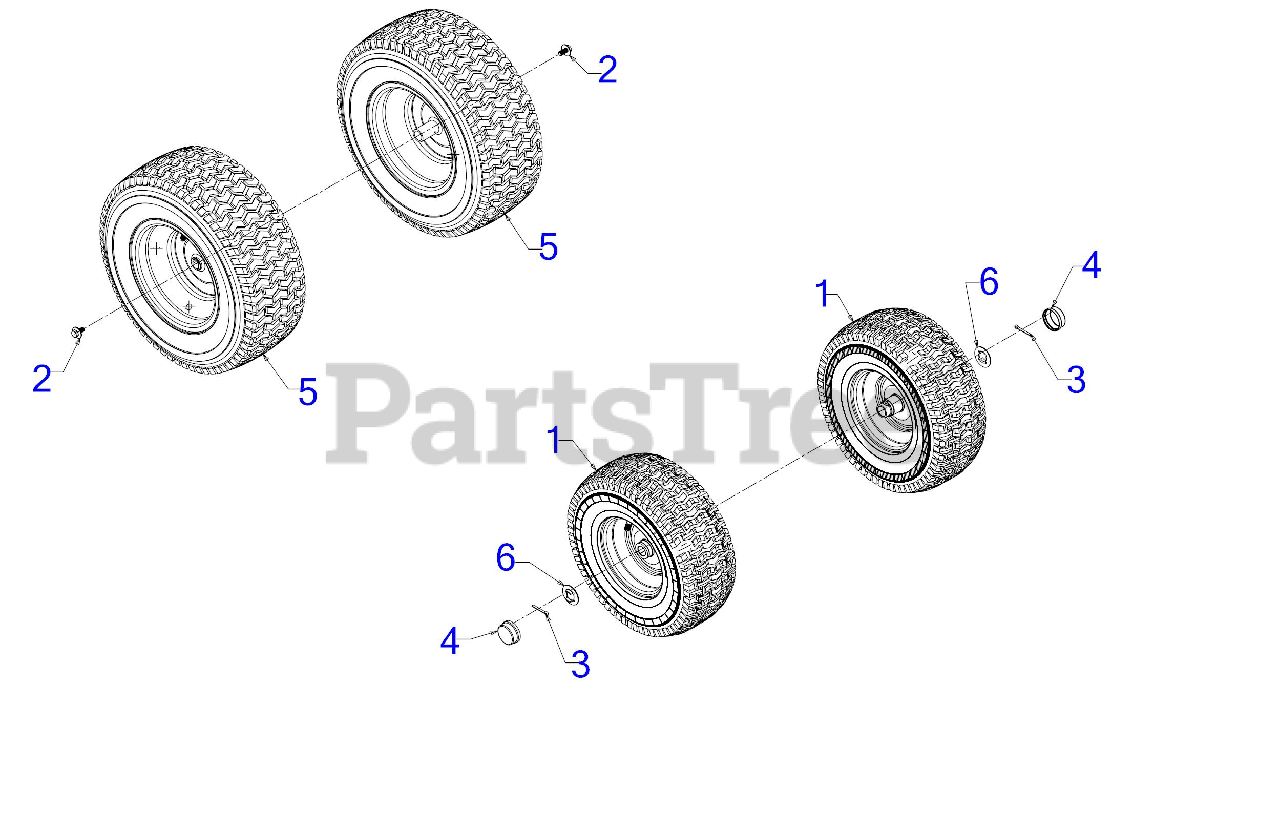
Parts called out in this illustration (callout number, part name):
2	SCREW 5/16-24 x .750 GR5
3	COTTER PIN-5/32 DIA
4	HUB CAP-BLACK
6	FLAT WASHER .781 ID X 1.59 OD
